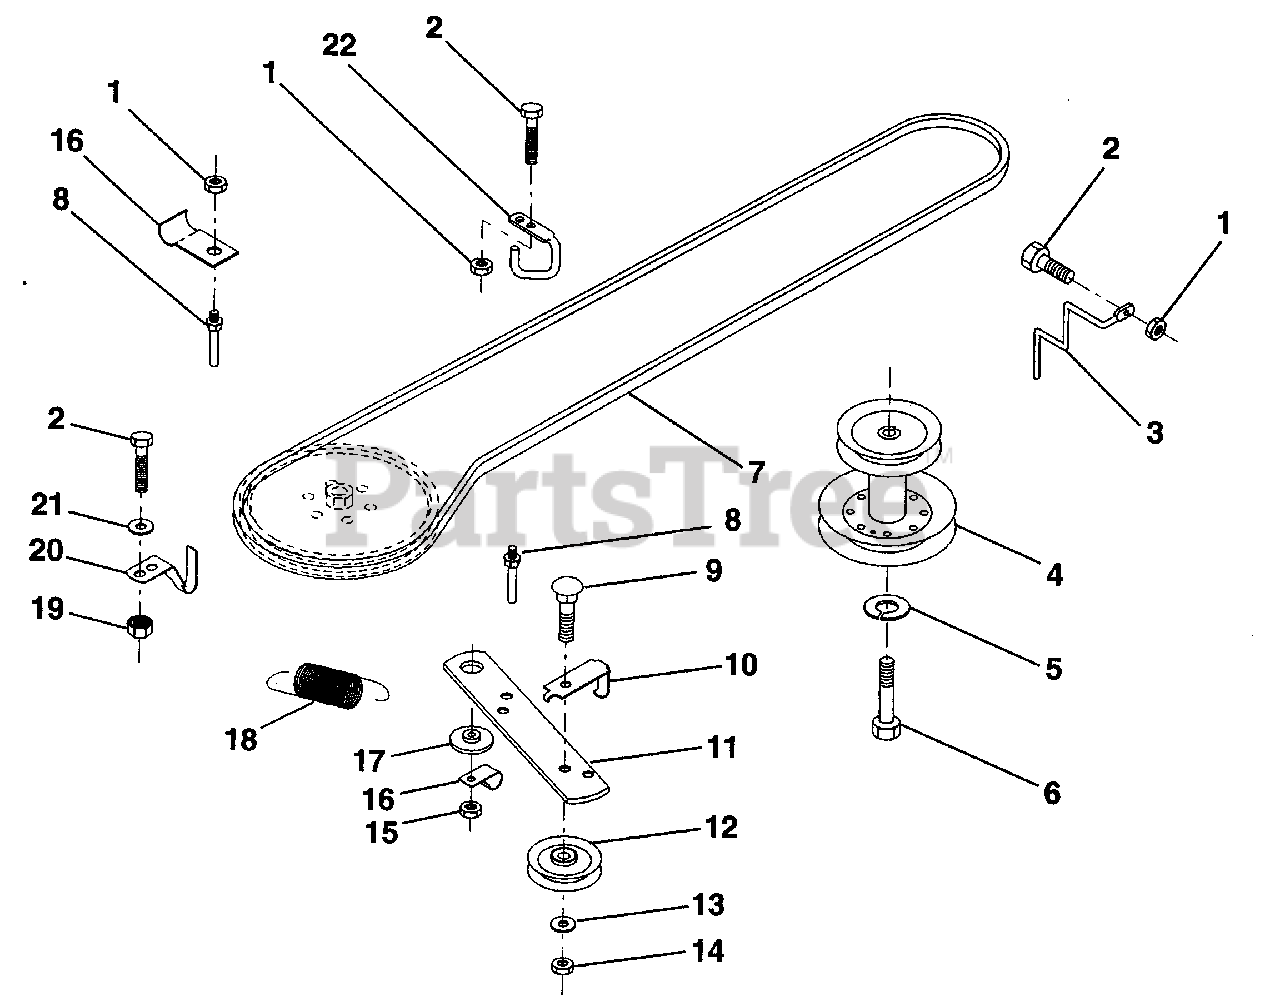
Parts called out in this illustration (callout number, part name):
1	Nut, Crownlock 5/16-18
2	Bolt, Hex 5/16-18 UNC x 3/4 (AYP part number)
3	Keeper, Mower Drive Belt, Engine (AYP part number)
4	Pulley, Engine (AYP part number)
5	Washer, Lock 7/16 (AYP part number)
6	Bolt, Hex, Fin 7/16-20 UNF x 3 (AYP part number)
7	Traction, V-Belt Drive (AYP part number)
8	Keeper, T/A Ground Drive Belt (AYP part number)
9	Bolt, Carriage 3/8-16 x 1-1/2 (AYP part number)
10	Keeper, Ground Drive Belt, Idler (AYP part number)
11	Arm, Ground Drive Clutch (AYP part number)
12	Idler, Flat (AYP part number)
13	Washer 13/32 x 13/16 x 16 Gauge (AYP part number)
14	Nut, Centerlock 3/8-16 UNC (AYP part number)
15	Nut, Crownlock 3/8-16 UNC
16	Clip, Insulated (AYP part number)
17	Spacer, Retainer (AYP part number)
18	Spring, Extension (AYP part number)
19	Nut, Keps 5/16-18 UNC (AYP part number)
20	Keeper, T/A Ground Drive Belt (AYP part number)
21	Washer 11/32 x 5/8 x 16 Gauge (AYP part number)
22	Keeper, Frame, Ground Drive Belt (AYP part number)
